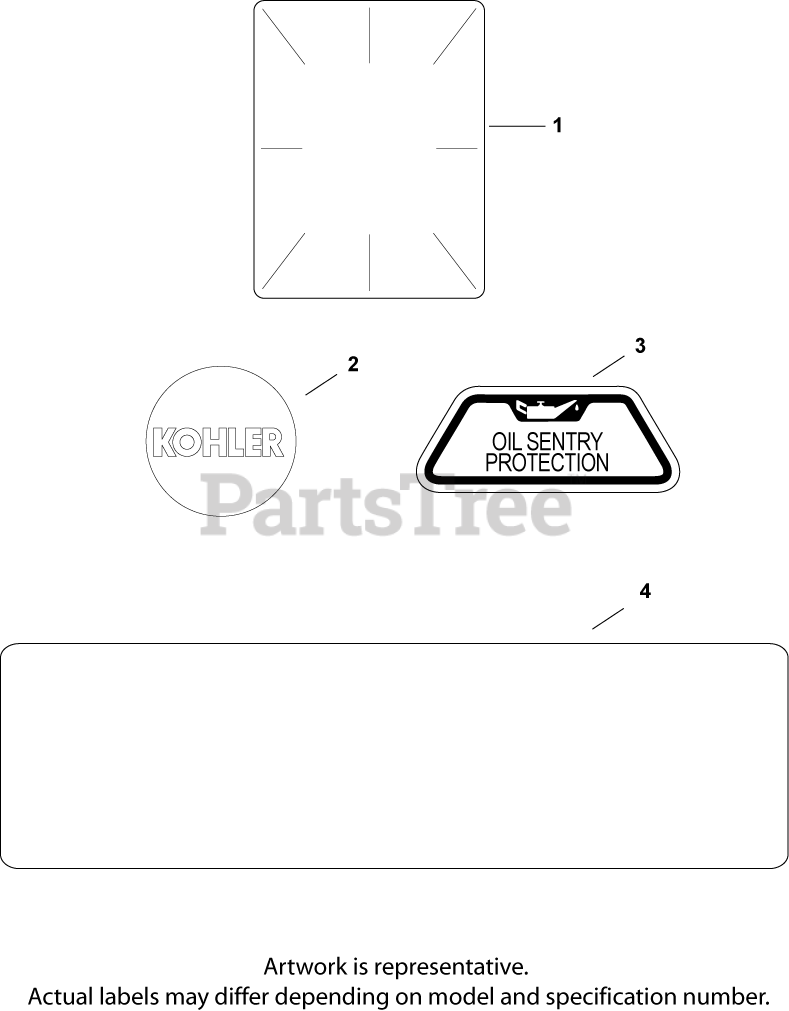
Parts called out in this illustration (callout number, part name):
1	DECAL, CLEAR LAMINATE USE 25 113 70-S
2	LABEL, (ROUND KOHLER GOLD)-USE 24 113 18
3	DECAL, OIL SENTRY - (#DSC)
4	DECAL, 20 HP
